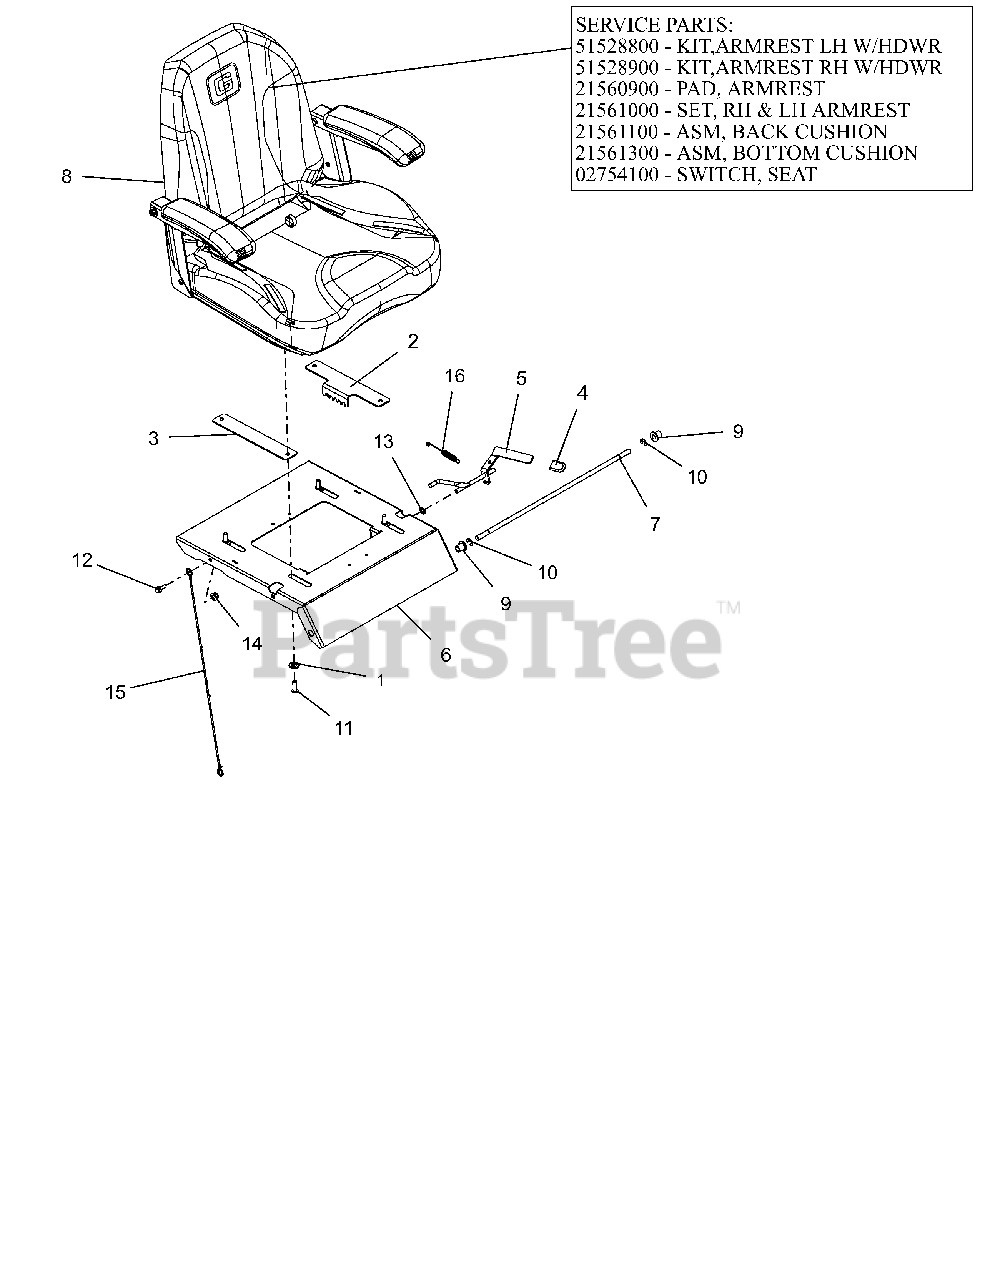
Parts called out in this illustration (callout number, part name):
1	BSHG, FLG .325X.499X.26X.88
2	PLATE, ADJUSTABLE SEAT TRACK
3	PLATE, ADJUSTABLE SEAT SLIDE
4	GRIP, SEAT LEVER, GREY
5	WLDMT, ADJUSTABLE SEAT LATCH
6	PLATE, SEAT
7	ROD, SEAT PIVOT
8	SEAT, ZTX 2017
8	KIT, ARMREST LH
8	KIT, ARMREST RH
8	PAD, ARMREST (HARD)
8	SET,RH & LH ARMREST -HARD
8	ASM,BACK CUSHION-GRAVELY X
8	ASM,BOTTOM CUSHION-GRAVELY X
8	SWITCH- SNAP MTG N.O.
9	BSHG-FLG .38X.580X.667X.750
10	RG-RTNG-EXT .375X.035 TYP E
11	SCR-SKH .31-18X1.0 BTNHD YWZC
12	BLT,HEX-FLG .25-20X.75 G5 BFP
13	NUT-PUSH .312
14	@NUT-LK-NYL-FLG .31-18 YWZC
15	LANYARD, SEAT CABLE .093X19.5
16	SG-TENS .043X.44X3.31 WLD 5.8
